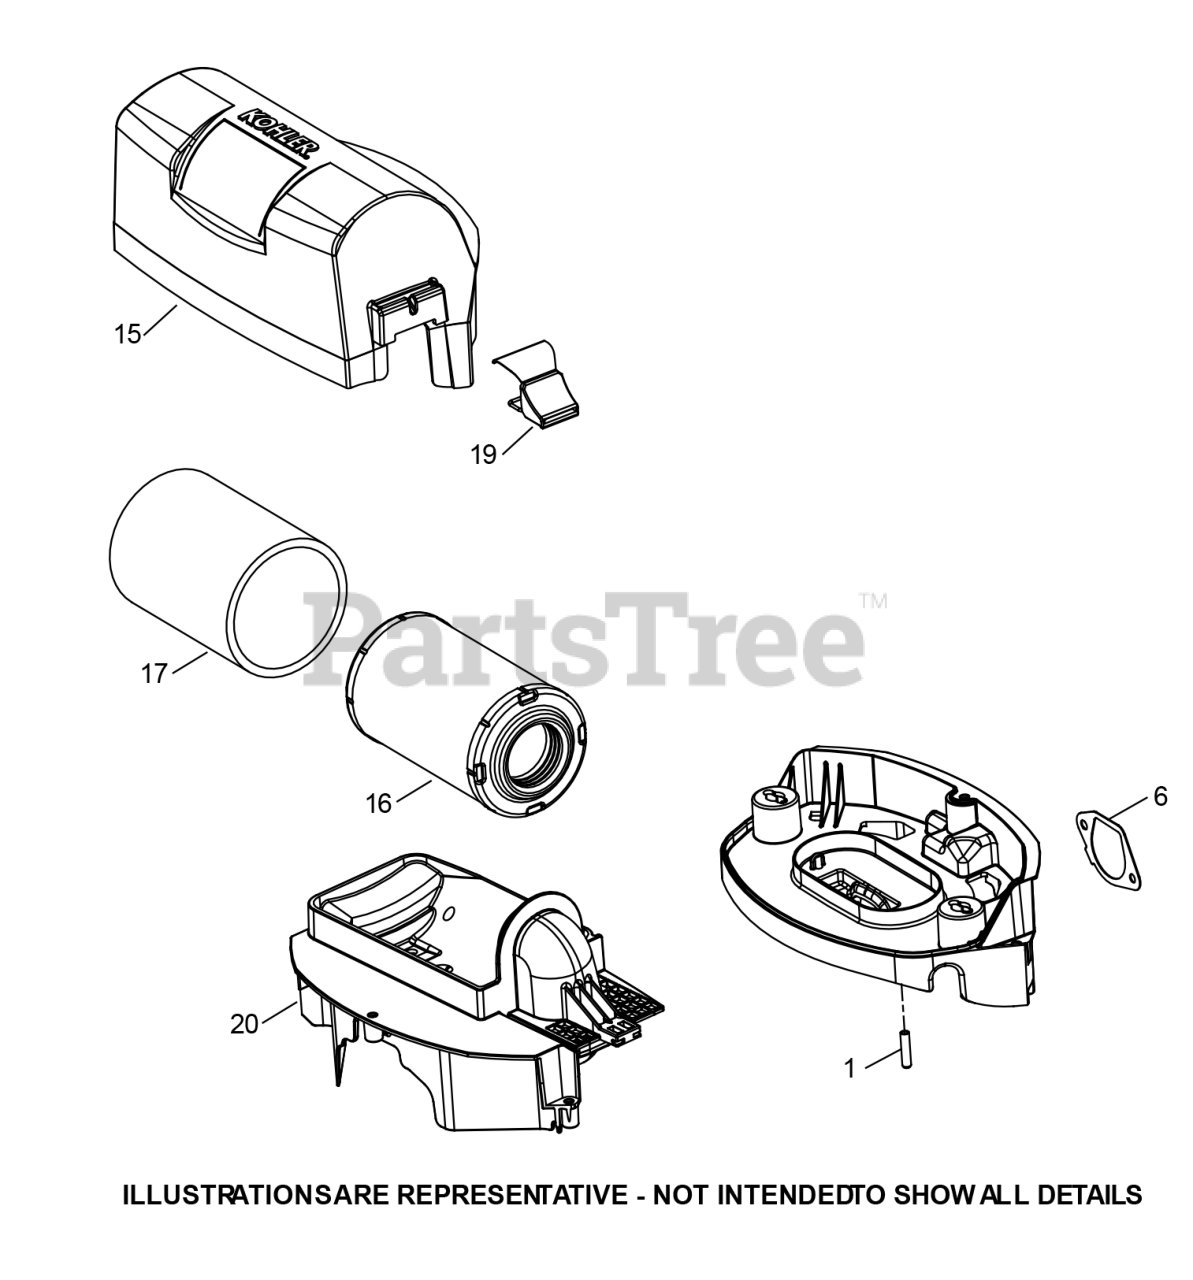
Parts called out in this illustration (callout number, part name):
6	GASKET-AIR CLNR BA
15	COVER, AIR CLEANER
16	AIR FILTER/PRECLEANER KIT
17	ELEMENT, PRE-CLEANER
19	AIR CLEANER COVER
20	AIR CLEANER BASE
